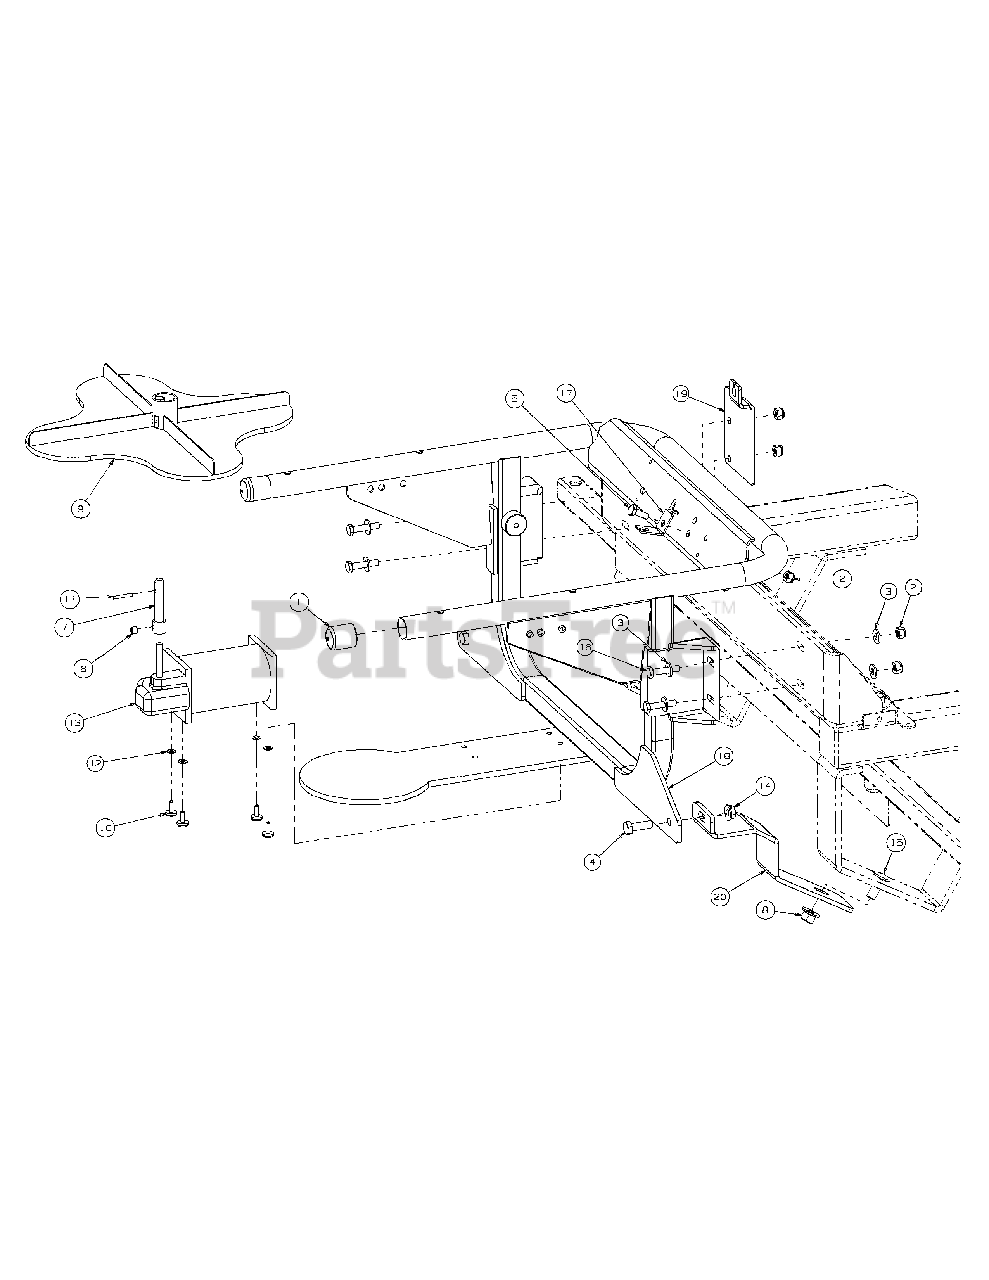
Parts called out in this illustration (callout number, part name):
2	Lock Nut, Nylon Insert, 1/4-20
3	Washer, 1/4
4	HHCS, 5/16-18 x 1.0
5	Hex Cap Screw, 1/4-20, .75
6	Set Screw
7	Motor impeller adapter
8	Hex Nut, 3/8-16 Flange Lock
10	8-32 x 1/2Phil. Hd. Scr.
12	# 8 Star Lock Washer
13	Motor (12 volt)
14	Nut, Lock, HexFlange, 5/16-18
15	Carriage Bolt, 3/8-16 x 1.00 Long
16	HHCS, 1/4-20 x 1.25
17	Brake Cable Mounting Bracket
18	Truckster Frame Assembly
19	Deflector Cable Mounting Bracket
20	Lower Support Brace
